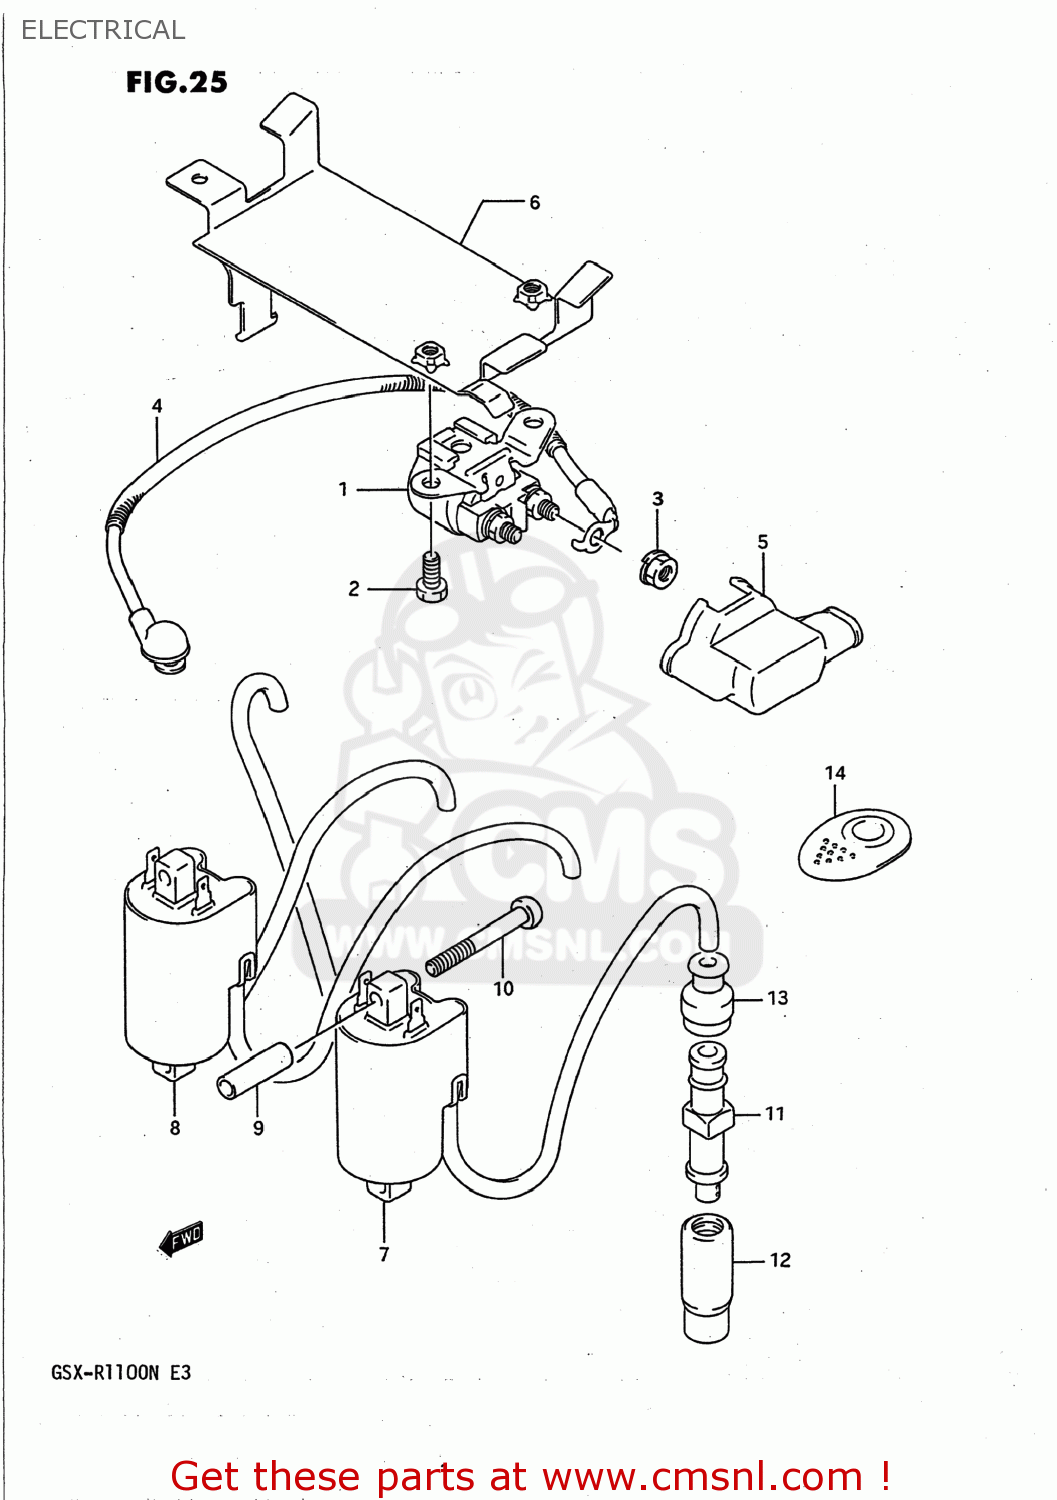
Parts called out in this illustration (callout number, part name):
1	RELAY ASSY,STARTING MOTOR
2	SCREW(6X8)
3	NUT
4	WIRE,STARTER MOTOR LEAD
5	CAP,STARTER RELAY
6	HOLDER COMP,ELECTRONIC PARTS
7	COIL ASSEMBLY,IGNITION
8	COIL ASSEMBLY,IGNITION
9	SPACER (6.5X10.5X31.7)
10	SCREW
11	CAP,SPARK PLUG
12	SEAL,SPARK PLUG
13	SEAL,HIGH TENSION CORD
14	COVER,SPARK PLUG CAP
